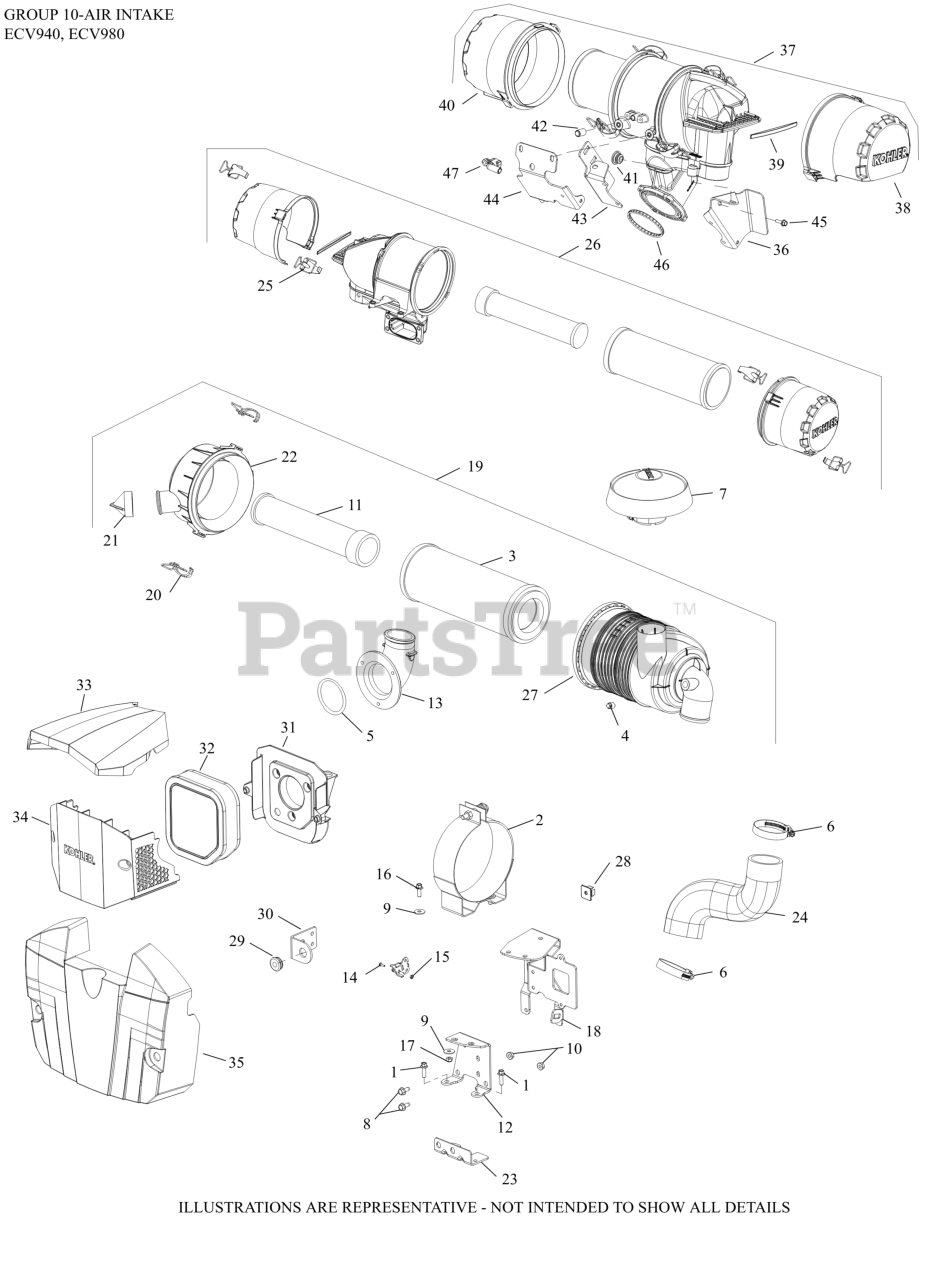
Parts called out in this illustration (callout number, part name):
1	SCREW, FLG M6x1.0x20
2	BRACKET, AIR CLEANER
3	ELEMENT, AIR FILTER - PRIMARY
4	PLUG, PIPE
5	O-RING, AIR CLEANER BASE
6	CLAMP, HOSE
7	HOOD, INLET
8	SCREW, THREAD FORMING
9	WASHER, FLAT 1/4"
10	NUT, FLG M6X1.0
11	ELEMENT, AIR FILTER - SAFETY
12	BRACKET,UPPER REMOTE A/C MOUNTING
13	ELBOW, MACHINING AIR CLEANER
16	SCREW, FLG M6X1.0X16
17	NUT, LOCK M6X1.0
18	BRACKET, LOWER REMOTE A/C MOUNTING
19	AIR CLEANER (W/DIRTY-SIDE EVAP FITTING)
20	LATCH ASSEMBLY
21	VALVE, VACUATOR
22	COVER ASSEMBLY
23	BRACKET, LIFTING
24	HOSE, AIR CLEANER
